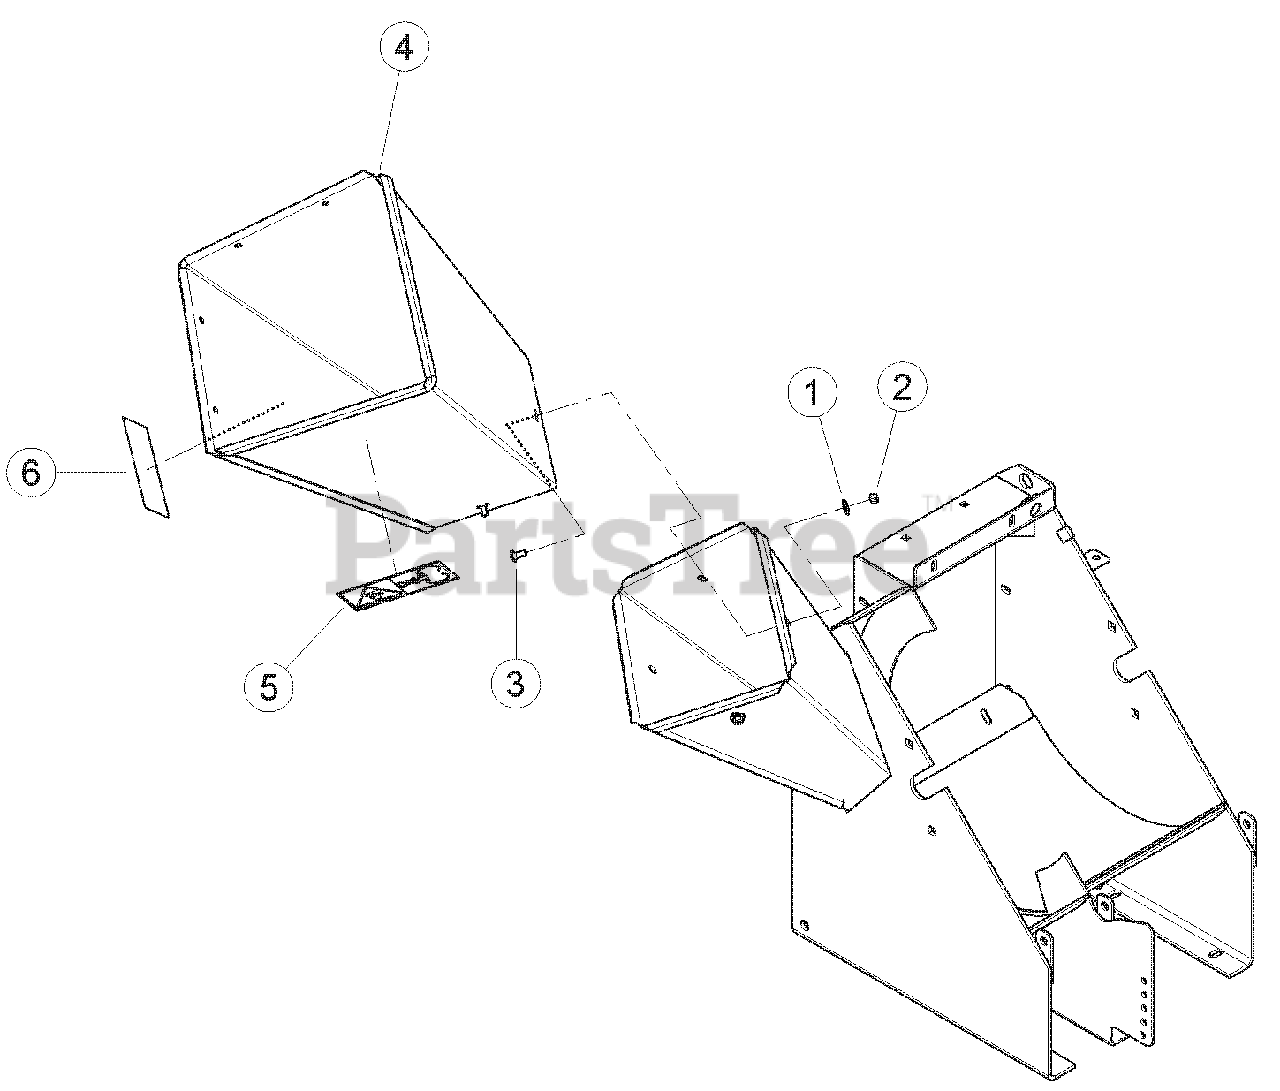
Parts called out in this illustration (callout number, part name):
1	WASHER, 5/16 FLAT ZP
2	NUT, 5/16 NE NYLOCK ZP
3	BOLT, 5/16 X 3/4 CRG GR5 NC ZP
4	ASSY, COMM CHUTE EXTENSION W/DECAL
5	DECAL, BLADE DANGER ISO
6	DECAL, MULTILINGUAL MANUAL
